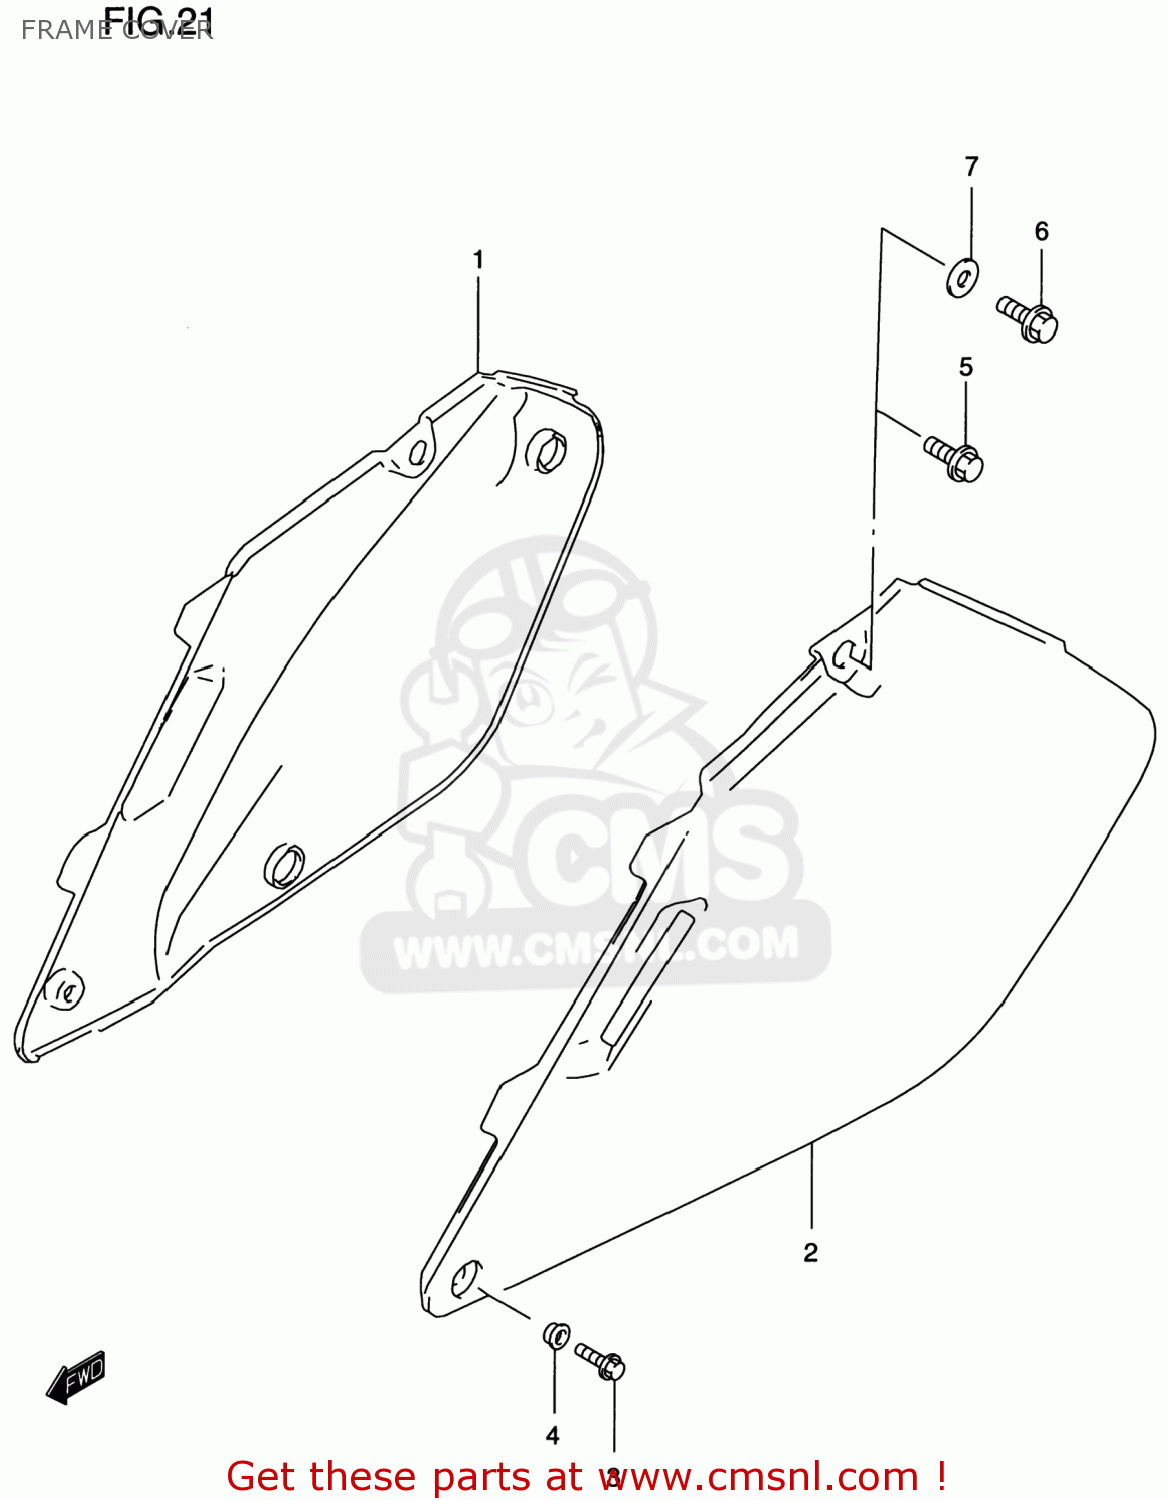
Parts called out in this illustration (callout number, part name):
1	COVER,FRAME,R(WHITE)
2	COVER,FRAME,LEFT
3	BOLT
4	WASHER
5	BOLT(6X16)
6	BOLT
7	WASHER
